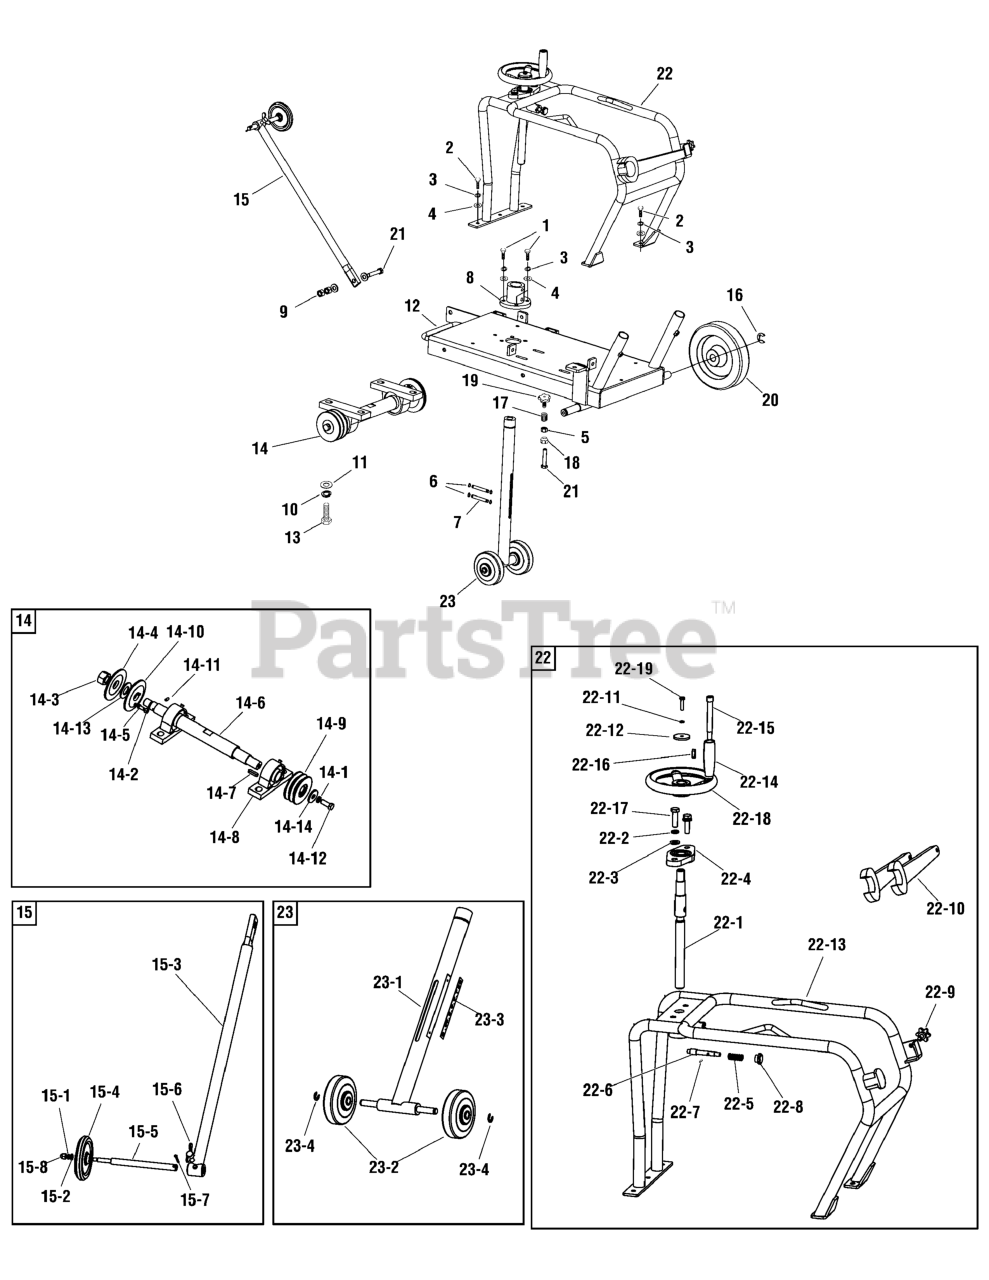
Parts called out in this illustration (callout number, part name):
1	BOLT, Hex, M8 x 30
2	BOLT, Hex, M8 x 25
3	WASHER, Spring, 8
4	WASHER, Flat, 8
5	NUT, Hex, M10
8	GUIDE PLATE
9	NUT, Hex, M12
10	WASHER, Spring
11	WASHER, Flat
12	BASE PLATE, Engine
13	BOLT, Hex, M12 x 45
14	BLADE SHAFT ASSEMBLY
14-1	WASHER, Spring
14-2	NUT, Hex, M8
14-3	NUT, Hex, Left, M22
14-4	BLADE FLANGE, Inner
14-5	BOLT, Blade
14-7	KEY, 8 x 35
14-8	BEARING
14-9	PULLEY, Belt
14-10	BLADE FLANGE, Outer
14-11	PIN, 6 x 12
14-12	BOLT, Hex, M12 x 30
14-13	WASHER, Blade
14-14	WASHER, Blade Shaft
15	GUIDE ROD ASSEMBLY
15-1	WASHER, Spring
15-2	WASHER, Flat
15-3	GUIDE ROD
15-4	WHEEL, Guide
15-5	SHAFT, Guide Wheel
15-6	NUT, Wing, M8 x 20
15-7	SPLIT PIN, 2 x 20
15-8	NUT, Acorn, M6
16	E-RING
17	SPRING, Return
18	COVER, Rubber
19	KNOB, Bolt, M10 x 50
20	WHEEL, Rear
21	BOLT, Hex, M10 x 50
22	TANK GUARD ASSEMBLY
22-1	THREADED ROD
22-2	WASHER, Spring, 10
22-3	WASHER, Flat, 10
22-4	BEARING
22-5	SPRING
22-7	PIN, Spring Type
22-8	KNOB, Nut, M8
22-9	KNOB, Bolt, M8
22-10	SPANNER
22-11	WASHER, Spring
22-12	WASHER, Flat
22-13	TANK GUARD
22-14	HANDLE, Return
22-15	BOLT, Return Handle
22-17	BOLT, Hex, M10 x 35
22-18	HANDLE WHEEL
22-19	BOLT, Hex, M6 x 25
23	CONNECTING ROD ASSMEBLY
23-1	CONNECTING ROD
23-2	WHEEL, Front
23-3	DECAL, Cutting Depth
23-4	E-CLIP
